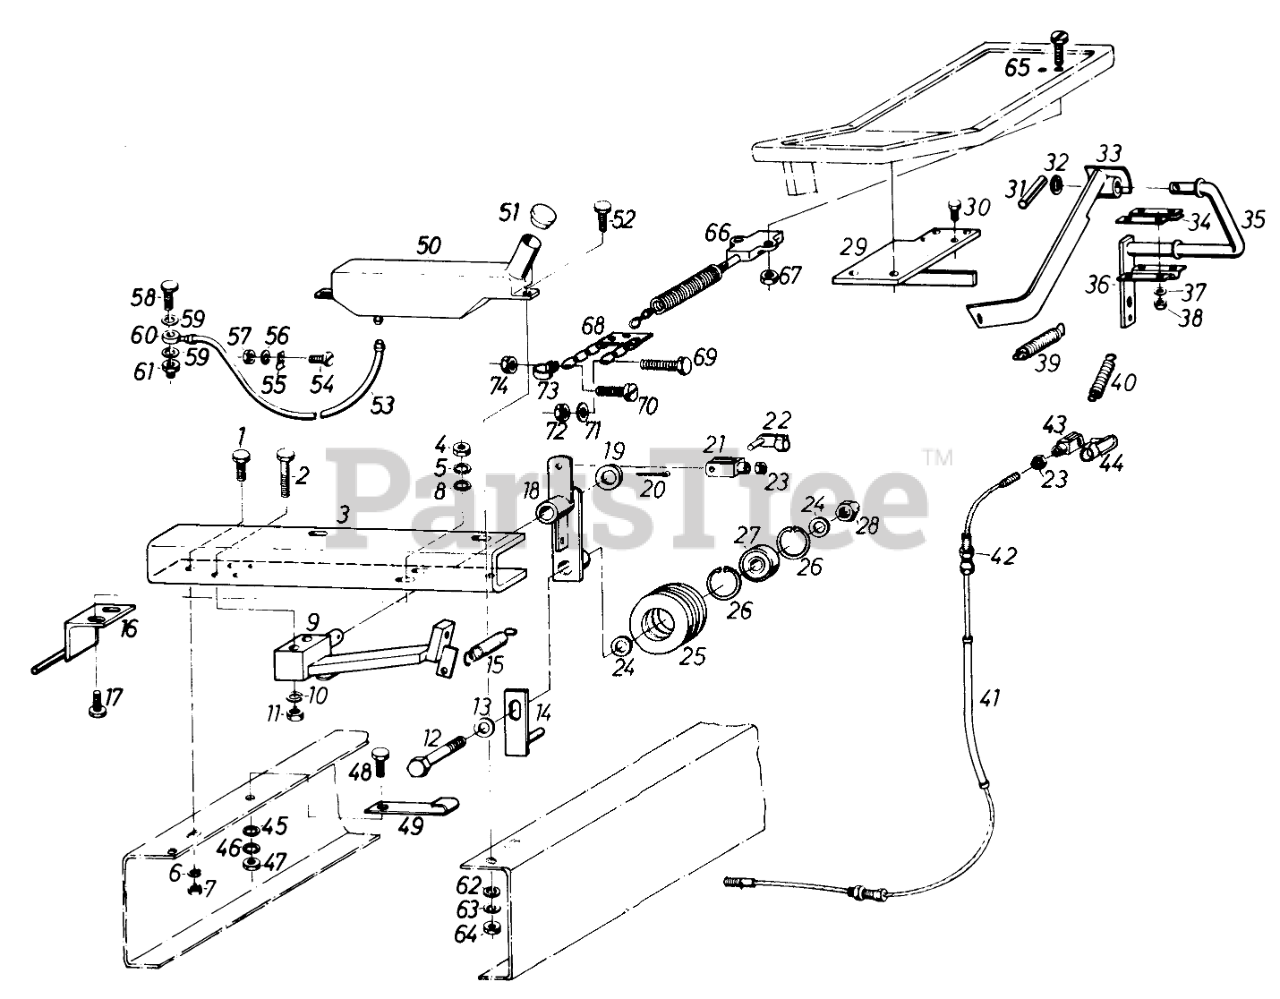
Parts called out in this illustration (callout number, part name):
2	Screw
3	Support
5	Lockwasher
6	Lockwasher
8	Washer
9	Bracket Assy
10	Washer
12	Screw
13	Washer
14	Belt Guide Assy.
15	Spring
16	Belt Guide Left
18	Tension Lever Assy
19	Washer
21	Yoke End
24	Washer
25	Tension Pulley
26	Retaining Ring
27	Ball Bearing
29	Support Plate
30	Screw
31	Spring Pin
32	Washer
33	Clutch Pedal Assy.
35	Pedal Support Assy.
36	Gas Pedal Bracket
37	Washer
39	Spring
40	Spring
41	Bowden Wire
43	Yoke End
45	Washer
46	Lockwasher
49	Belt Guide
50	Oil Reservoir
51	Cap and Gasket
54	Screw
55	Clamp
56	Washer
58	Screw
59	GASKET
60	Nipple
60	Clamp
62	Washer
63	Lockwasher
65	Screw
66	STOP LIGHT SWITCH
68	Bracket Assy.
69	Screw
70	Screw
71	Washer
73	Clamp
